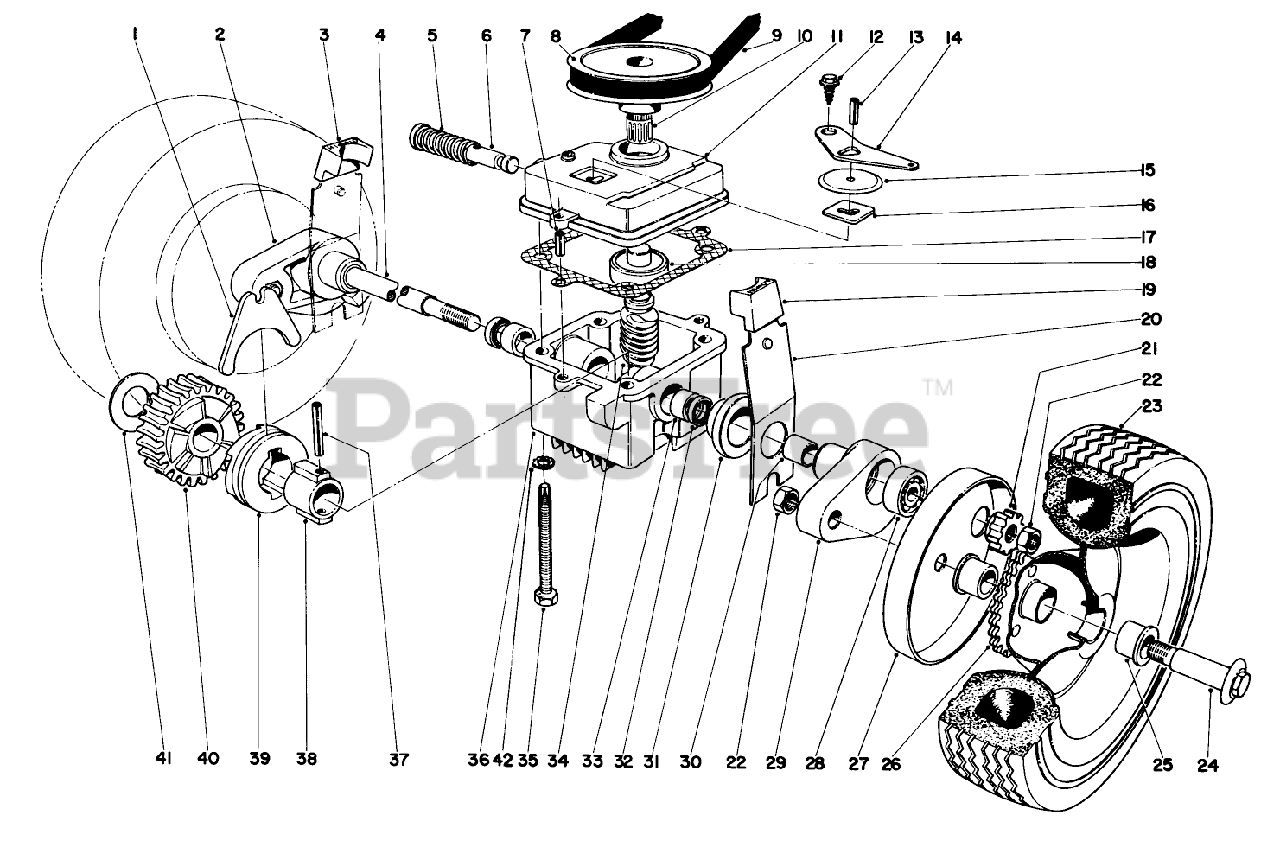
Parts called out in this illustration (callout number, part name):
1	SHIFTER FORK
2	Pivot Arm (Incl. No. 30)
4	DRIVE SHAFT
5	SPRING
6	Shift Rod
7	3/16 X 1/2 ROLL PIN
8	PULLEY
9	Belt
10	TOLERANCE RING
11	GEAR CASE COVER
12	Screw
13	PIN-ROLL
14	SHIFTER ARM
15	TRANS DUST COVER
16	LATCH PLATE
17	GASKET
18	Bearing
19	ARM KNOB
20	Spring Arm
21	PINION GEAR
22	NUT-HEX
23	8 TIRE
24	Wheel Bolt
25	Bushing
26	Wheel Assembly
27	WHEEL COVER
28	.375 RPP BALL BEARING
29	Pivot Arm (Incl. No. 30)
30	BUSHING
31	End Cap
32	Seal
33	Bushing
34	Worm Shaft
35	Sems Screw
36	Gear Case
37	PIN-SPRING
38	SLEEVE
39	Clutch
40	Worm Gear
41	THRUST WASHER
42	WASHER-LOCK/EXT
